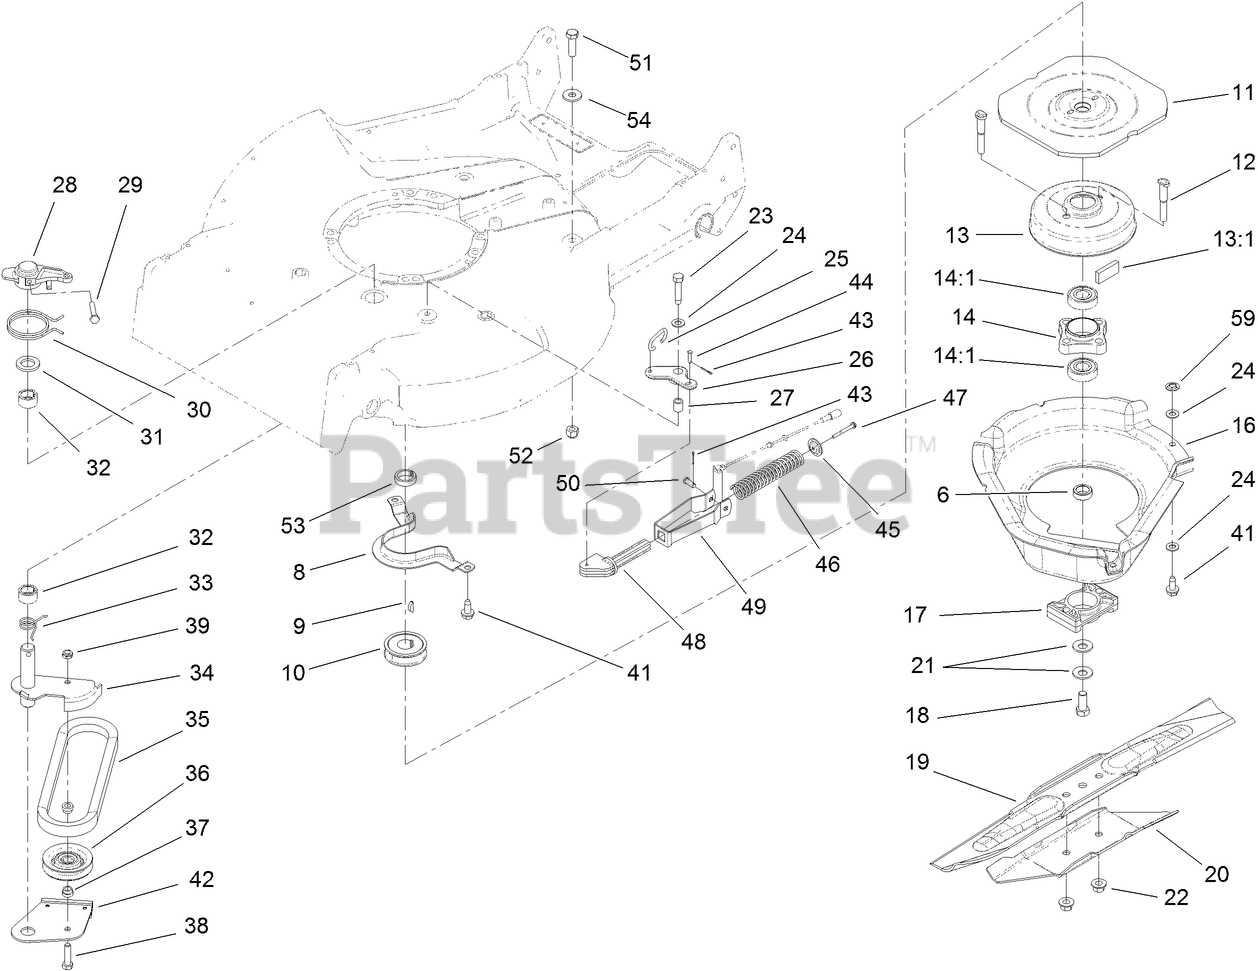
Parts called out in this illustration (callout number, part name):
6	SPACER-SHAFT, OUTPUT
8	BRACKET-GUIDE, BELT
9	KEY-WOODRUFF
10	PULLEY-DRIVER
11	FLYWHEEL - BBC
12	BOLT-BLADE
13	BRAKE DRUM ASM
13:1	DAMPENER-VIBRATION
14	HUB ASM
16	SHIELD
17	SPACER-BLADE
18	SCREW-HH
19	BLADE-21 INCH
20	STIFFENER-BLADE
21	WASHER-SPRING
22	NUT-LOCK
23	SCREW-HH
24	WASHER-PLAIN
25	LINK-CONTROL
26	BELLCRANK
27	SLEEVE-BELLCRANK
28	LEVER
29	SCREW-HH
30	SPRING-TORSION
31	WASHER
32	BEARING
33	SPRING-TORSION
34	ARM-IDLER
35	V-BELT
36	PULLEY-IDLER
37	SPACER-PULLEY, IDLER
38	SCREW-HH
39	NUT-LOCK, NI
41	SCREW-HWHTF
43	PIN-COTTER
44	PIN-SPRING
45	RETAINER-SPRING
46	SPRING
47	SCREW-HWHTF
48	GUIDE-SPRING
49	BRACKET-SPRING
50	PIN-CABLE
51	SCREW-HH
52	NUT-LOCK, NI
53	SPACER-PULLEY
54	WASHER-HARDENED
59	NUT-PUSH
